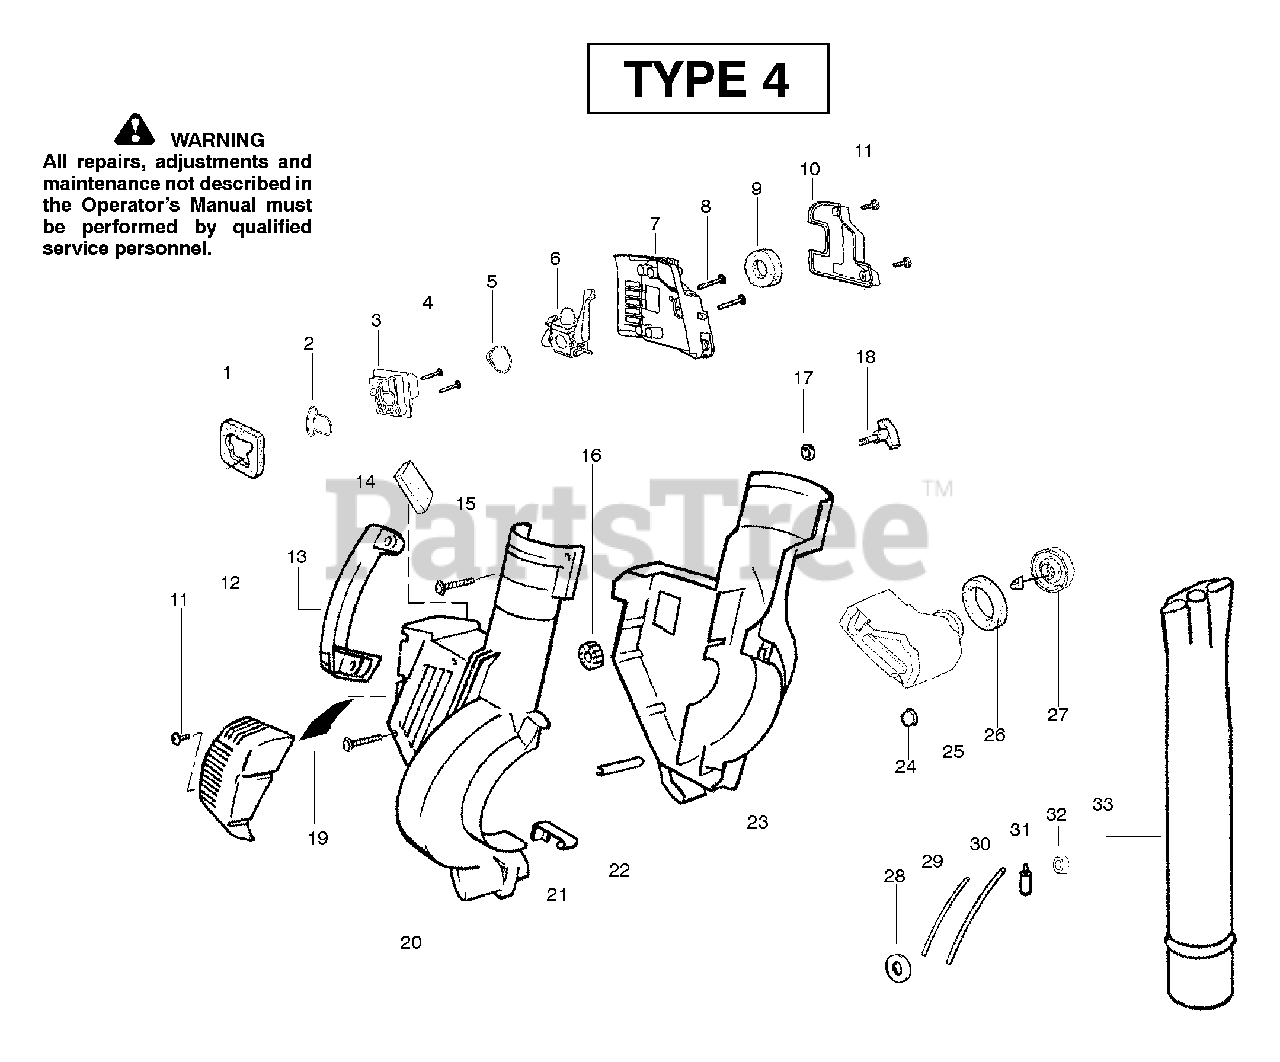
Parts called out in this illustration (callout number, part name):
1	Air Dam (kit)
2	Gasket-Adaptor (kit)
3	Carburetor Adaptor
5	Gasket-Carburetor (kit)
6	Kit-Carb Ass'y Zama-(C1Q-W11C)
6	Kit-Carb Ass'y Walbro-(WT-606)
8	Screw-Carb.
9	Filter-Air
10	Cover-Air Filter
12	Guard-Muffler
14	Foam - 71.12mm (kit)
16	Isolator
18	Knob-Tube Clamp
19	Reflector-Heat (kit)
20	Housing-Right
21	Spring-Cover Latch
22	Guide-Starter Rope
23	Housing-Left
24	Isolator-Crankcase
25	Assy-Fuel Tank
26	Gasket-Fuel Tank
27	Fuel Cap w/Retainer
28	Grommet-Shroud
29	Kit-Line Carb/Purge
30	Kit-Line Tank/Purge
31	Assy-Fuel Pick-up
32	Grommet-Fuel line (kit)
33	Tube-Blower
